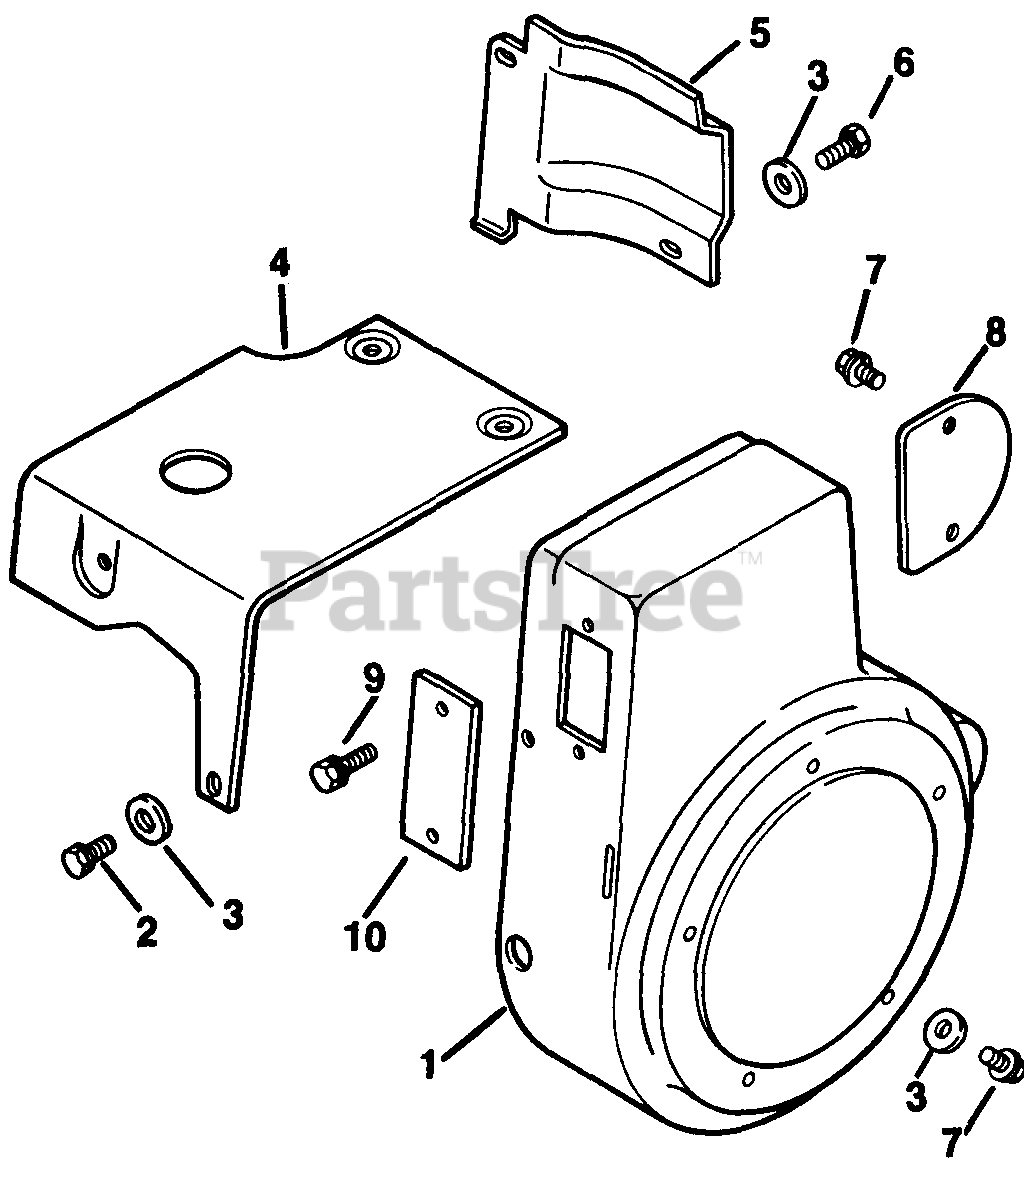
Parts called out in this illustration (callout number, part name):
2	SCREW - DISCONTINUED
3	WASHER, FLAT 1/4" (O.D. 5/8")
4	BAFFLE - USE 41 063 11
5	BAFFLE - DISCONTINUED
6	SCREW - DISCONTINUED
